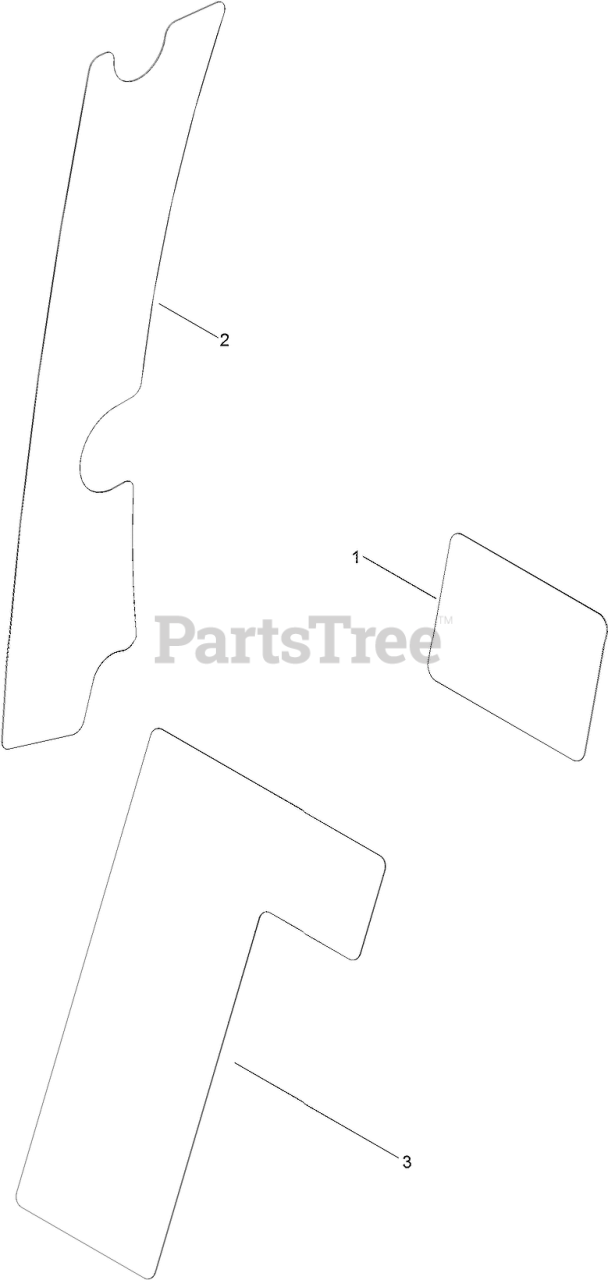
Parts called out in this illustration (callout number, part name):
1	DECAL-MAINTENANCE
2	DECAL-HOC
3	DECAL-SMART SPEED
